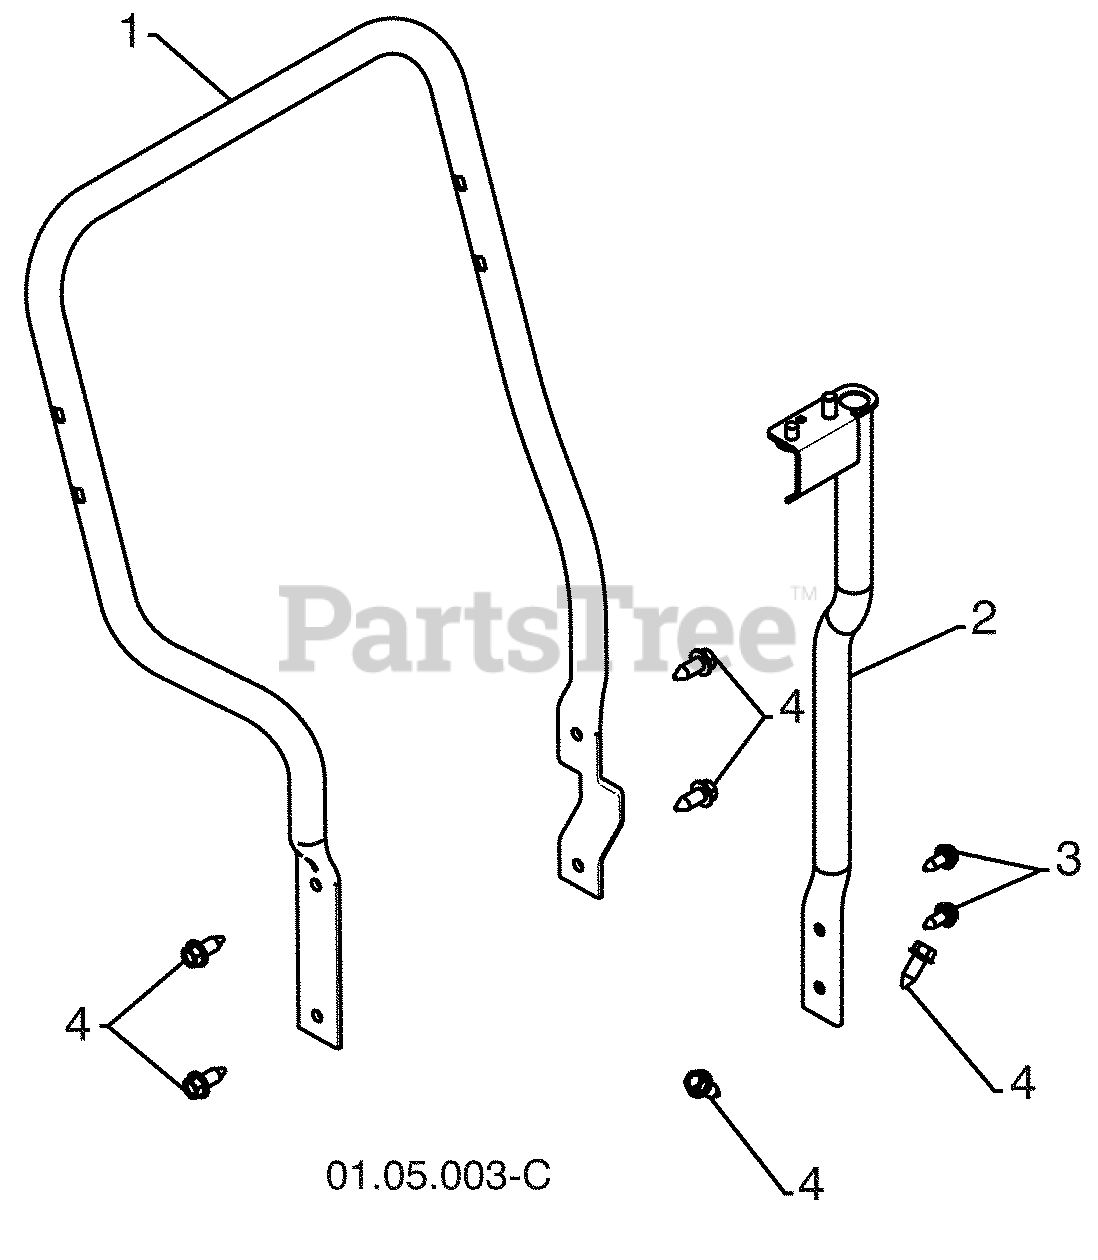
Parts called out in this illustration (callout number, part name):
1	LOWER TUBE
2	PIVOT SUPPORT
3	BOLT 5/16-18 X .750
4	SCREW 3/8-16 X 1 .00
